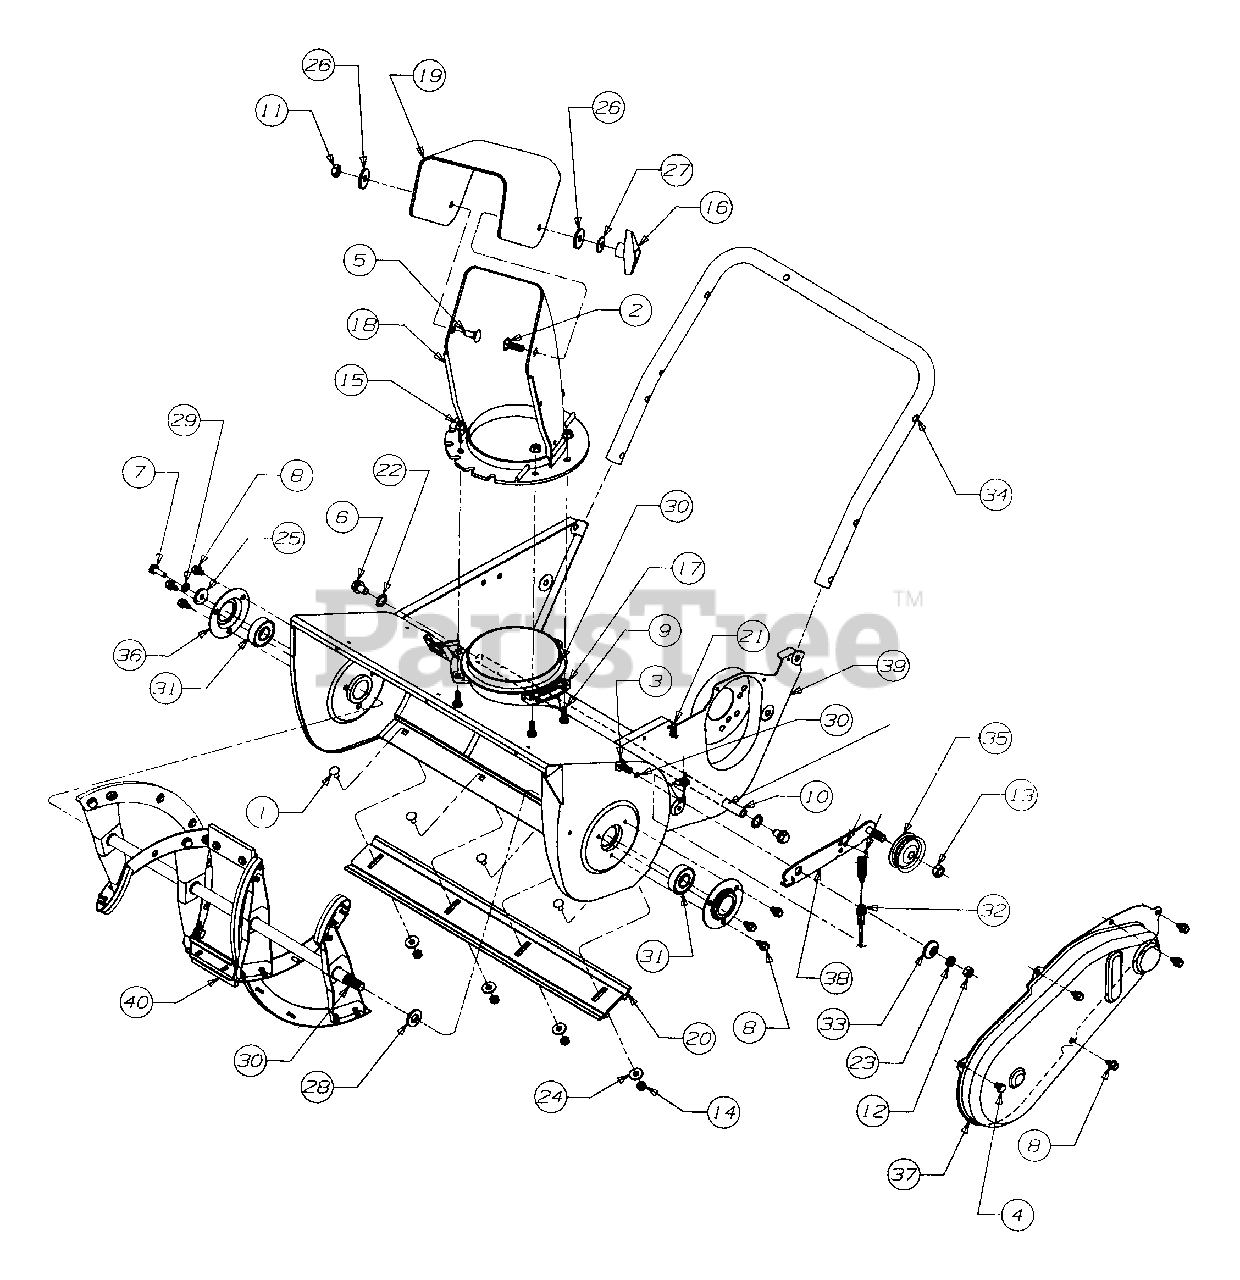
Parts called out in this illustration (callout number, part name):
1	Bolt - Carriage
2	Bolt - Carriage
3	Screw - Truss Machine
4	Screw - Hex B-Tap
5	Bolt - Carriage
6	Screw - Wash. Self-Tap
7	Screw Hex Wash.
8	Screw - Hex L-Wash Hd.
9	Hex Head Cap Screw
10	Axle - Wheel
11	Nut - Hex Center Lock
12	Nut - Hex
13	Nut - Hex Lock
14	Nut - Hex Jam
15	Nut - Lock
16	Knob - Wing Nut
17	Keeper - Chute Flange
18	Chute Lower
19	Chute Upper
20	Plate - Shave
21	Spring - Extension
22	Washer - Flat
23	Washer - Lock
24	Washer - Flat
25	Washer - Flat
26	Washer - Flat
27	Washer - Bell
28	Washer - Flat
29	Washer - Lock
30	Plastilube #0 1402
31	Bearing - Ball
32	Cable - Clutch
